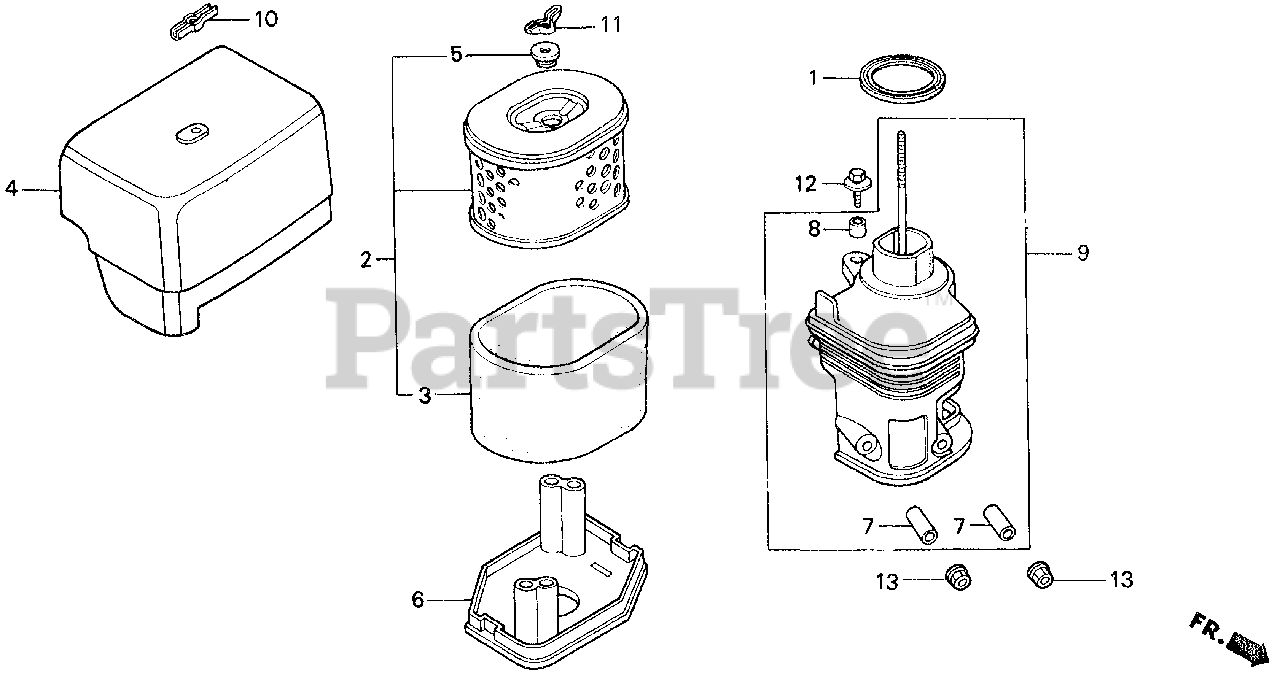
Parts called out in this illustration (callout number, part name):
1	GASKET, ELBOW
2	ELEMENT, AIR CLEANER
3	FILTER (OUTER)
4	COVER, AIR CLEANER
5	GROMMET, AIR CLEANER
6	NOSE, MUFFLER
7	COLLAR, AIR CLEANER
8	COLLAR B, AIR CLEANER
9	ELBOW, AIR CLEANER
10	WINGNUT, TOOL BOX SETTING
11	WINGNUT, TOOL BOX SETTING
12	BOLT-WASHER (6X22)
12	BOLT-WASHER (6X20)
13	NUT, FLANGE (6MM)
